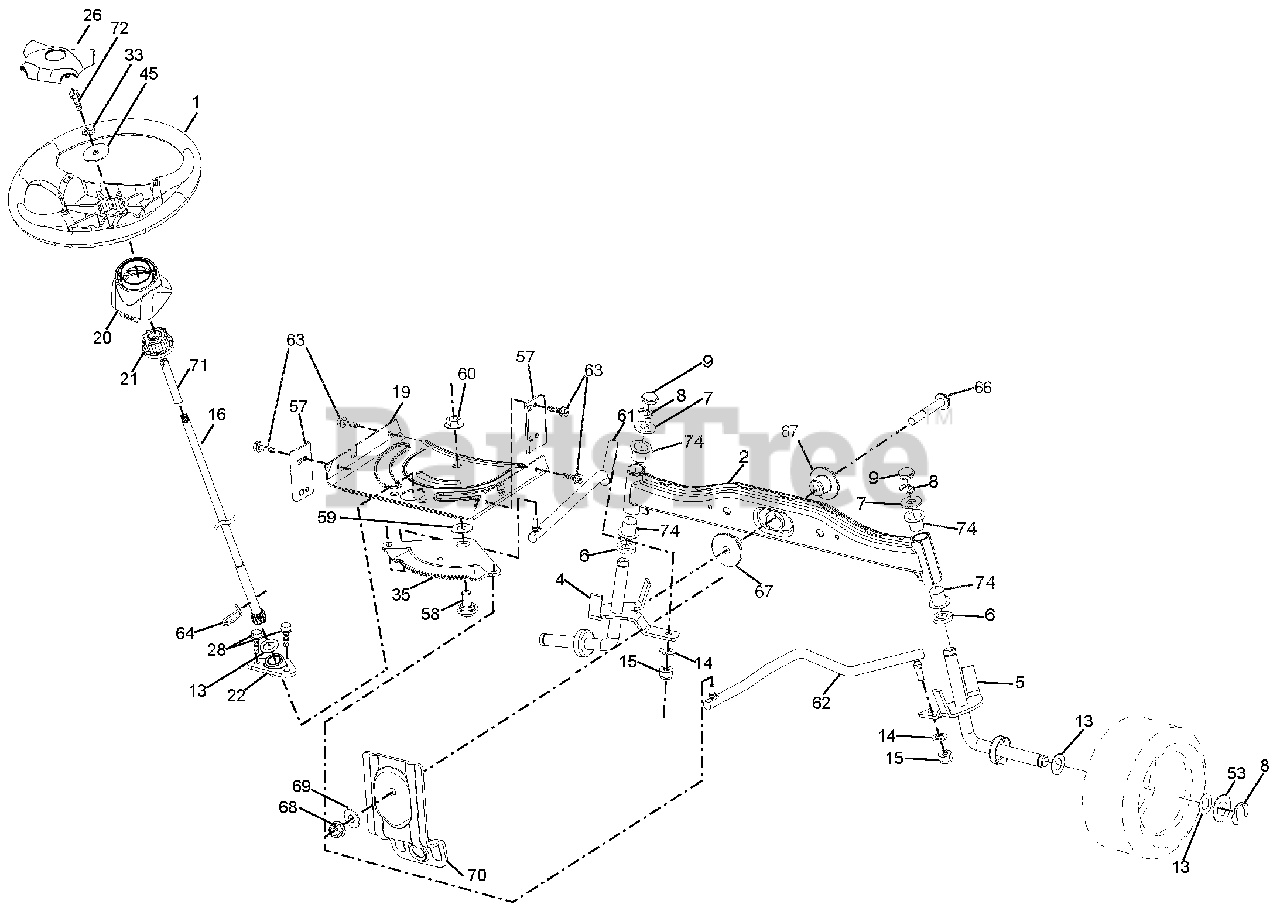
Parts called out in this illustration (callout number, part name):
1	WHEEL.STEERING.HARD RIM.BLACK
2	AXLE ASM.WELDED
4	SPINDLE.WELDED.LH.15"TEX
5	SPINDLE.WELDED.RH.15"TEX
6	WASHER.THRUST..75 X 1.230
7	WASHER.25/32 X 1-5/8 X 16GA.
8	RING.KLIP.#T5304-75
9	CAP.SPINDLE.FR.TOP.BLK.
13	WASHER.25/32 X 1 1/4 X 16 GA.
14	Washer, Lock 3/8
15	NUT.CROWNLOCK.3/8-24
16	SHAFT.STEER.5/8 TEX.NON-PLATED
19	PLATE.STEER.DDL.NLT/NGT
20	BOOT.STEERING.LT.TEX P/L.428
21	ADAPTER.WHEEL.STRG..760
22	BUSHING ASM STEERING.ALUM.NLT
26	CAP.WHL.STRG.HRS/SRS.BLACK
28	SCREW.HEXWSH THDR3/8-16X3/4.BL
33	Washer, Lock 5/16
35	GEAR SECTOR.PLATE.DDL.NLT/NGT
45	WASHER.11/32ID X2 3/8OD X 12GA
53	WASHER.HARDEN..793 X 1.637X060
57	BRACKET.UPSTOP.TEX
58	BOLT.SHOULDER.SECTOR.PIVOT.CFM
59	WASHER.THRUST.SECTOR.STEER.NLT
60	NUT.FLANGE LOCK.5/8-11
61	DRAGLINK.LH.BALLSTUD.DDL.
62	DRAGLINK.RH.BALLSTUD.DDL
63	SCREW.5/16-18X3/4.SMGML.TAP/BL
64	RETAINER.CLIP.SPRING.STEERING
66	BOLT.HEX.FGHD.7/16-14 X 3.SERR
67	BUSHING.PM.FRONT AXLE
68	NUT.LOCK.FLANGE.7/16-14.GR5
69	WASHER.1.5 X .505 X .118
70	BRACKET.DECK.SUSPENSION.FRONT
71	SHAFT.EXTEN.STRG.SPLINE.TEX
72	BOLT.FIN.HEX.5/16-18UNCX4.5.G5
74	BEARING.COL.STRG.BLK.
